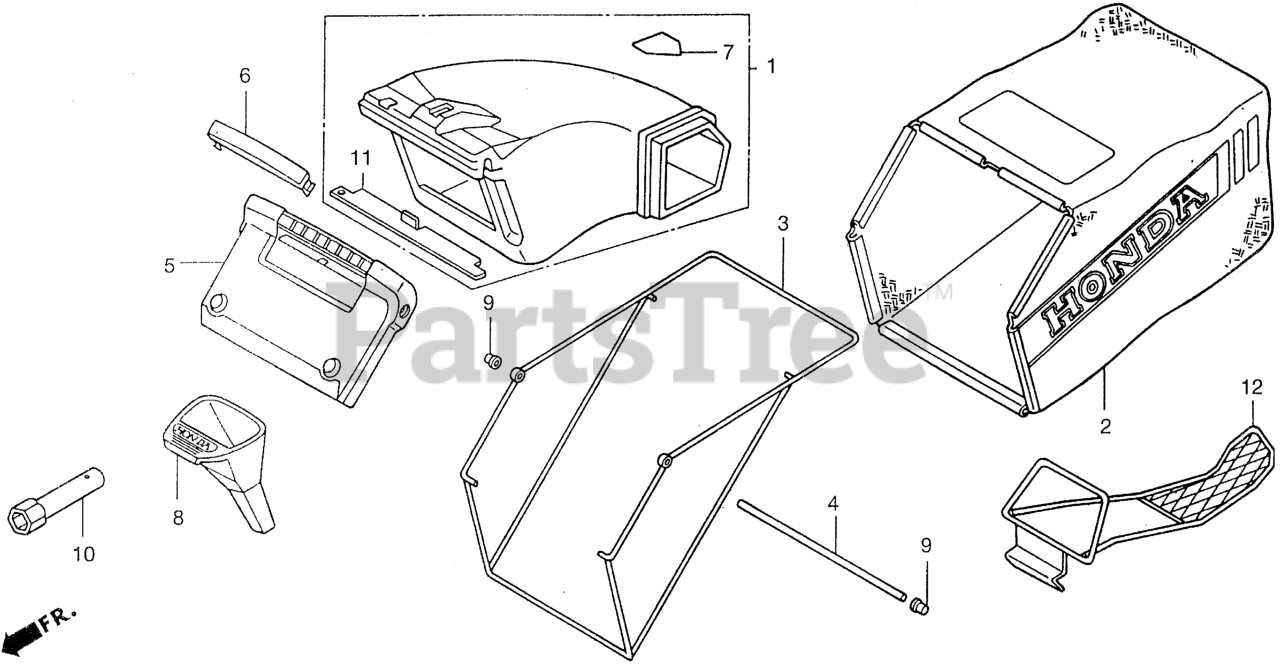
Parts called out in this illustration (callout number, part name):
1	CHUTE KIT, SIDE DISCHARGE
2	FABRIC, GRASS BAG
3	FRAME, BAG (LOWER)
4	JOINT, GRASS BAG
5	CATCHER, GRASS (UPPER)
6	COVER, GRASS CATCHER GRIP
7	LABEL C, HOUSING CAUTION
8	FUNNEL, OIL
9	NUT, PUSH (8MM)
10	WRENCH, BOX (P21)
11	BRACKET, MOUNTING (NOT AVAILABLE)
